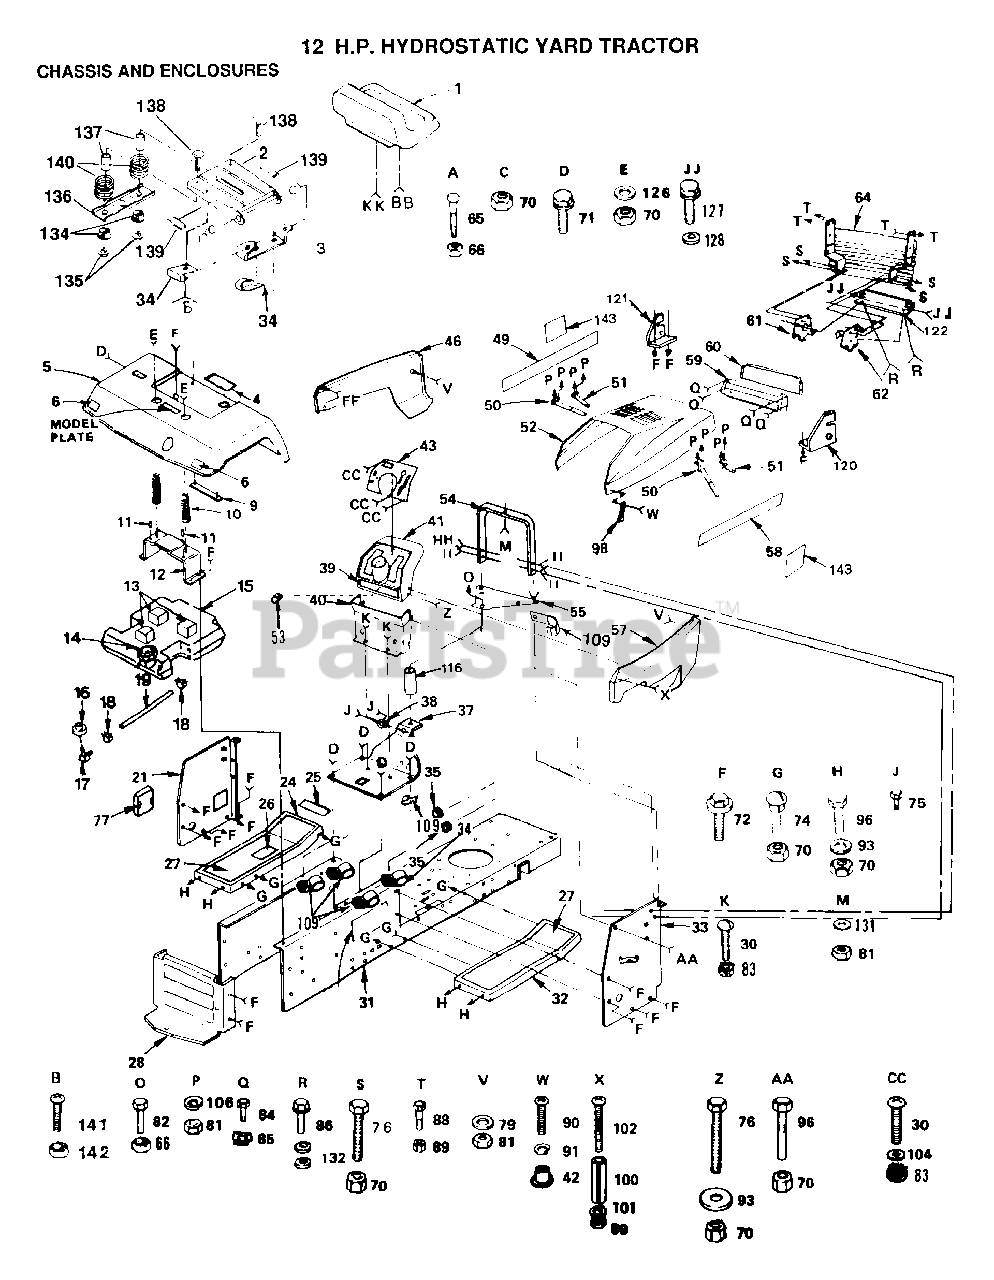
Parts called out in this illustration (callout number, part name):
6	REFLECTOR-TAIL YT
11	NUT-PUSH YT
12	BRKT FENDER T
13	PAD-SPACER T
16	BUSHING OUTLET T
17	FUEL TANK STEM GT
21	DASH PANEL T
25	DECAL T
27	PAD FOOTREST T
30	SCREW
37	SADDLE
39	DECAL YT
40	LOWER DASH
42	WELDNUT
49	DECAL - HOOD L.H.
53	PLUG BUTTON T
58	DECAL - HOOD, R.H.
60	LENS LT
61	SUPPORT LH YTH
62	SUPPORT RH YTH
71	SCREW LT
72	SCREW
74	BOLT
76	BOLT
77	COVER ACCESS
79	WASHER PM
82	BOLT
85	"""J"" FASTENER LT"
86	SCREW
88	BOLT T
90	SCREW
91	LOCKWASHER
93	WASHER
98	HOOD LATCH T
100	SPACER LT
101	WASHER
102	SCREW
104	WASHER
109	CLIP T
116	SPACER
120	SUPPORT RH YTH
121	SUPPORT LH YTH
126	WASHER
127	SCREW
128	WASHER PM
132	WASHER
134	BUSHING
135	NUT T
136	BRKT SWITCH
137	SPACER SPLIT
138	BOLT
142	"NUT,KEPS"
